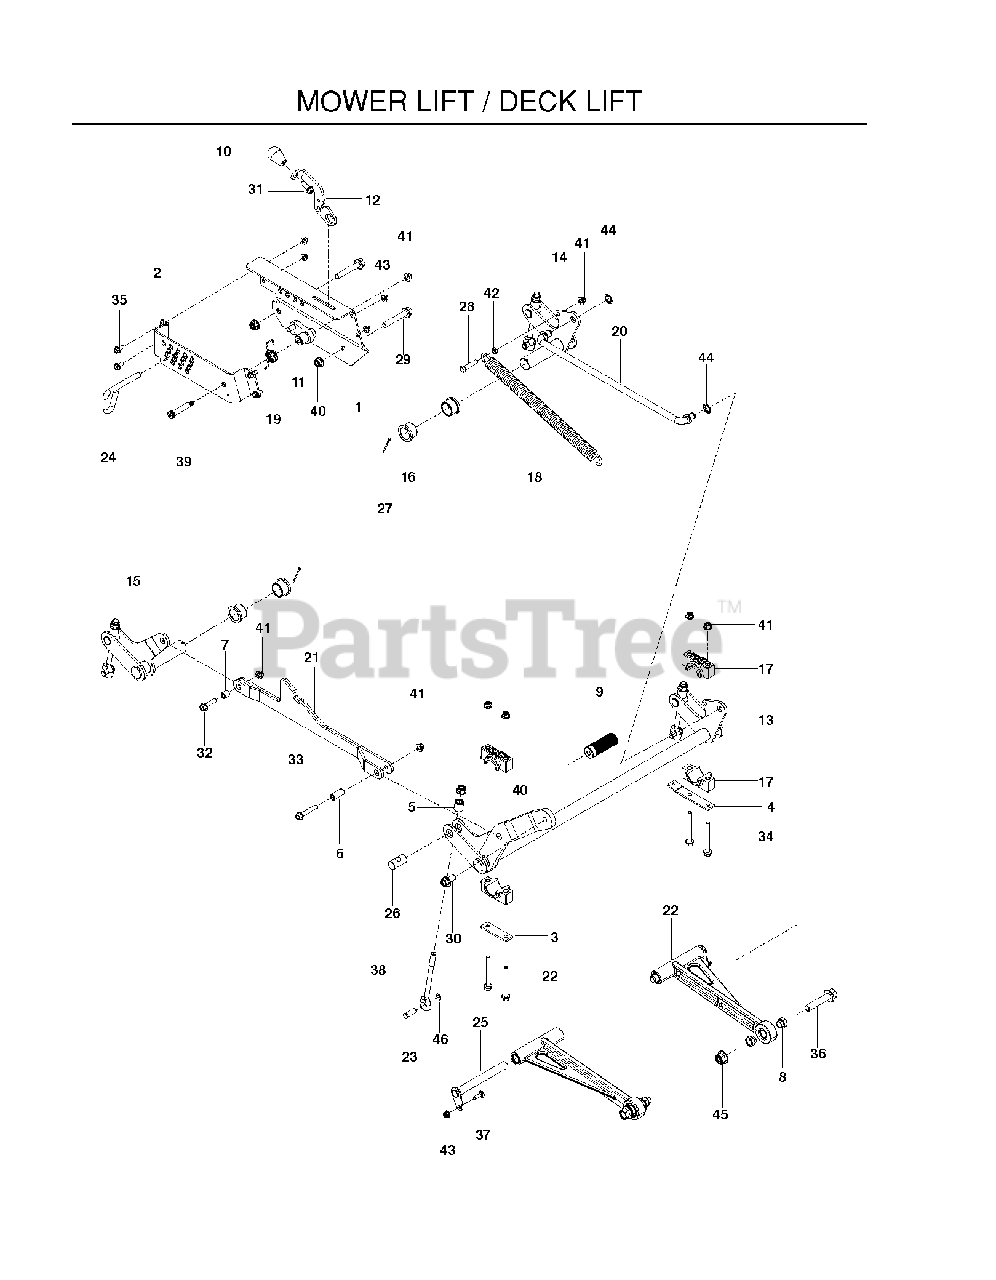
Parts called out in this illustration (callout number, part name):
1	PLATE, HEIGHT INNER ORG
2	PLATE, HEIGHT OUTER ORG
3	PLATE, PILLOW BLACK
4	PLATE, SPRING ANCHOR
5	SPACER, EYEBOLT
6	SPACER, FRONT LIFT STRAP
7	SPACER, REAR LIFT STRAP
8	SPACER, STRUT
9	PEDAL, DECK HEIGHT
10	KNOB - SHIFT
11	LATCH, TRANSPORT WLDMT
12	LEVER, TRANSPORT RELEASE
13	SHAFT DECK LIFT FT
16	BUSHING, FLANGE 1.25 X 1.0
17	BLOCK, PILLOW
18	SPRING, EXTENSION
19	SPRING, TORSION
21	WELDMT, DECK STRAP
22	ASSEMBLY, STRUT
23	PIN, 7/16 CLEVIS
24	PIN, HEIGHT
25	PIN, STRUT
26	PIN, TRUNION, EYEBOLT
27	COTTER PIN 1/8 X 2
28	HCS 3/8-16 X 1 3/4 GR5
29	HFFS 1/2-13 X 3 GD 5 ZD
30	HHFS 1/2-13 X 1 GR5 ZD
31	HHFS 3/8-16 X 1 GRD 5 ZD
32	HHFS 3/8-16 X 1.50 GR5 ZD
33	HHFS 3/8-16 X 2-1/4 GR 5 ZD
34	HHFS 3/8-16 X 3.5 GD 5 ZD
35	HHFS 5/16-18 X 3/4
36	HHFS 5/8-11 X 3.0 GD 8 ZD
37	RHSNB 5/16C X 1
38	EYEBOLT, DECK LIFT
39	BOLT, SHOULDER, 1/2 X 2.25
40	NUT, 1/2-13 HEX FLG NYLOC ZD
41	NUT 3/8-16 HEX FLG NYLOC ZD
42	NUT 3/8-16 HEX JAM
43	5/16-18 NYLOC FLANGE NUT
44	NUT 5/8 PUSH
45	NUT 5/8-11 FLG NYLOC ZD
46	RING, E, 7/16
